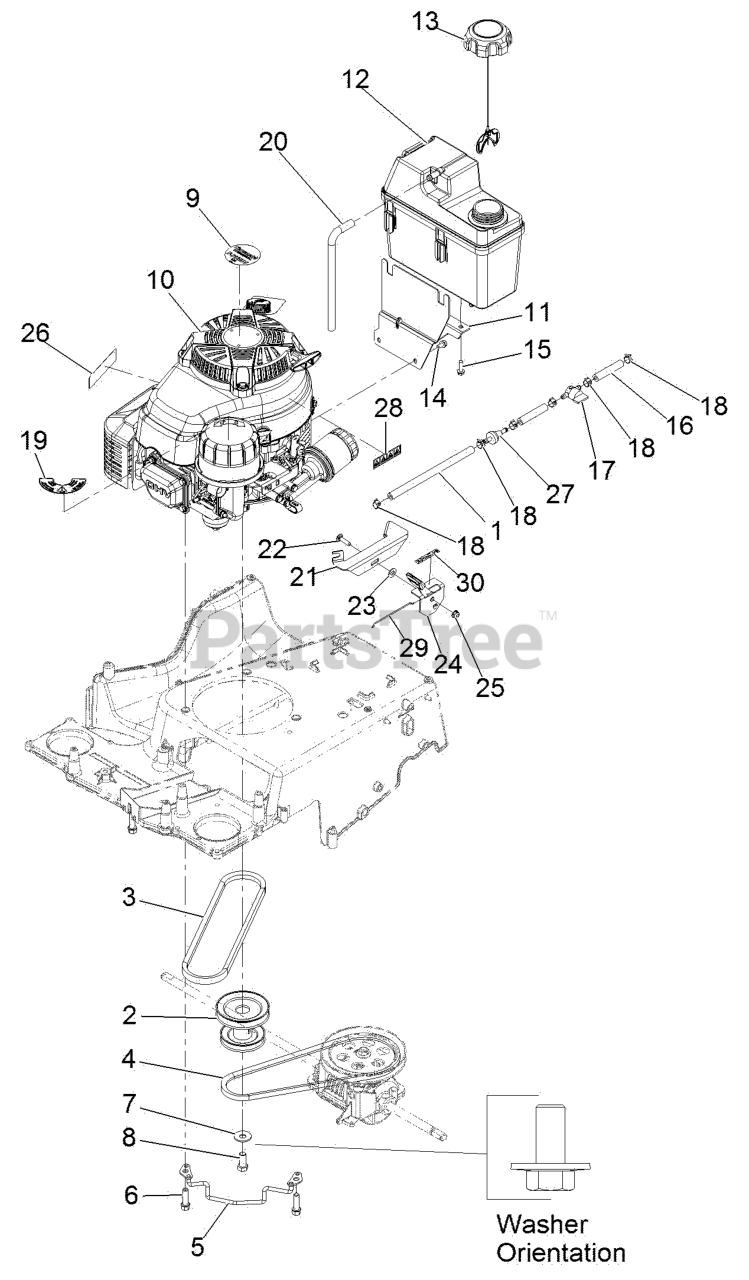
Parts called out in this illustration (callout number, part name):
1	HOSE-FUEL
2	PULLEY-ENGINE
4	BELT
6	SCREW-TAPTITE
7	WASHER-BELLEVILLE
8	SCREW-HH
11	MOUNT-TANK
14	SCREW-HWH
15	SCREW-HWH
16	HOSE-FUEL
17	VALVE-FUEL
18	CLAMP-HOSE
20	HOSE-VENT, CANISTER
21	BRACKET-MOUNT, THROTTLE
22	SCREW-CARR
23	WASHER-PLAIN
24	CONTROL-THROTTLE
26	DECAL-ARRESTER, SPARK
27	FILTER-FUEL
28	DECAL-WARNING, ENGINE
29	WIRE-CONTROL
30	DECAL-THROTTLE, CHOKE
